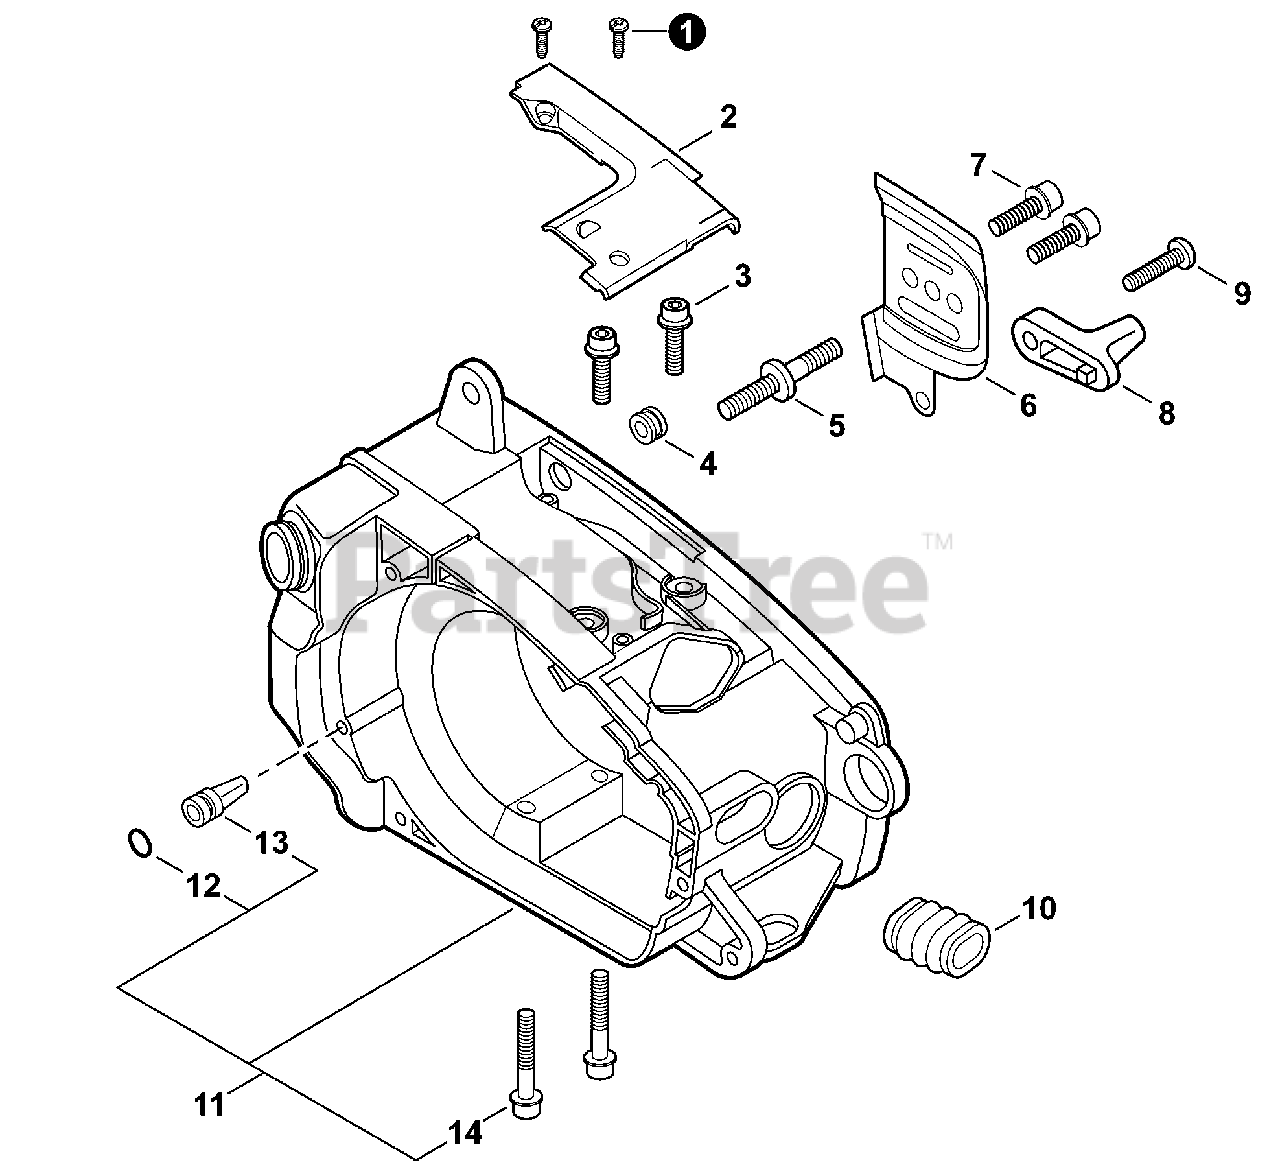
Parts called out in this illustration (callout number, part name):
1	SCREW 4×12
2	COVER, DUST
3	BOLT 5×18
5	BOLT, STUD 8
6	PLATE, GUIDE - INNER
7	BOLT 4×12
8	CHAIN CATCHER
9	SCREW 5×20
10	BELLOWS, INTAKE
11	COVER, ENGINE
12	O-RING S-4
13	VENT ASSY
14	BOLT 5×25
